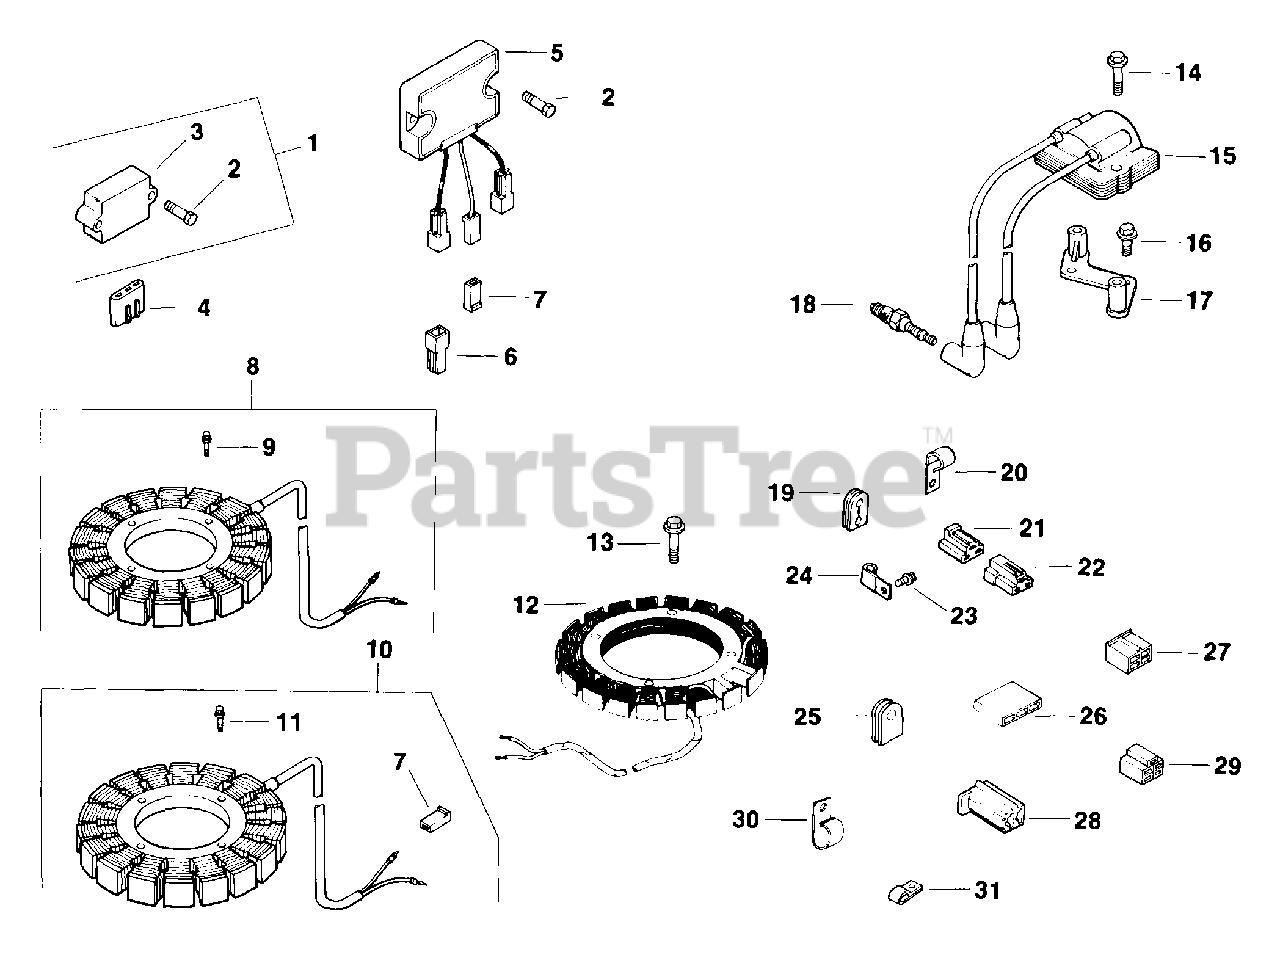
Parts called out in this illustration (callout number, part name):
1	KIT, REGULATOR/RECTIFIER
2	SCREW, SEMS 1/4-20X5/8" USE 25 086 539-S
3	REG/RECT-15 AMP (KM)-USE 41 403 10-S
8	KIT, 15 / 20 AMP STATOR
9	SCREW, WSH HD TAP #10-24X3/4" USE 25 086 97-S
14	SCREW, WSH HD 1/4-20X7/8" - DISCONTINUED
16	SCREW, WSH HD 1/4-20X1"
17	BRACKET - DISCONTINUED
18	SPARK PLUG - USE 52 132 02
19	GROMMET - (#DSC)
20	CLIP, CABLE
21	CONNECTOR
26	CONNECTOR, BODY (KM)-USE 25 155 41-S
